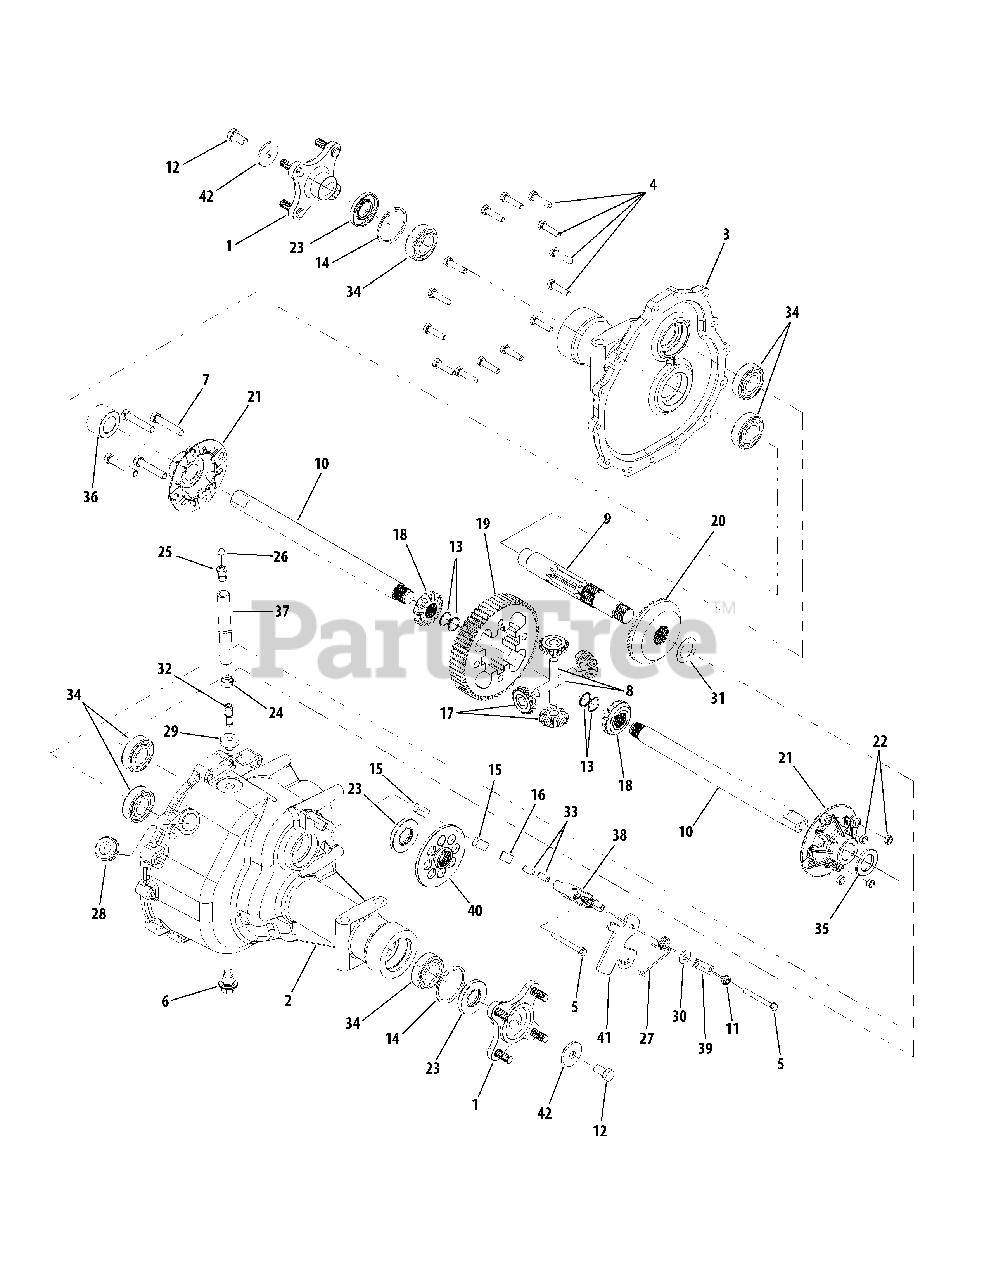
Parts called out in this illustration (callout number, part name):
1	Hub Ass’y, Wheel
2	Housing, RH Transmission
3	Housing, LH Transmission
4	Screw, Hex Cap Lock, 5/16-18 x 1.25 GR5
5	Screw, Hex Wash Hd. Tapp, 1/4-20 x 2.375
6	Screw, Plug, M14 x 1.5 x .827
7	Screw, Hex Cap Lock, 3/8-16 x 2.0 GR5
8	Shaft, Cross, .50 x 3.005
9	Shaft, Output, 9T
10	Shaft, Axle
11	Nut, Hex Nylon Lock, 5/16-24
12	Screw, Hex Cap Lock, 3/8-16 x .75 GR5
13	Ring, Retaining
14	Ring, Retaining
15	Pad, Brake
16	Plate, Puck
17	Gear, Miter, 10T
18	Gear, Miter, 14T
19	Gear, Differential Spur, 60T
20	Gear, Bevel, 54T
21	Housing, Differential w/Thru Holes
22	Nut, Hex Insert Jam GR5, 3/8-16
23	Seal, Oil, 1.0 x 2.047 x .2755
24	Clamp, Hose
25	Vent, Plastic
26	Cap, Plastic Vent
27	Spring, Torsion
28	Grommet, Rubber, .75 x 1.063
29	Grommet, Rubber, .362 x .56
30	Washer, Flat, .343 x .88 x .062
31	Washer, Thrust, 1.007 x 1.542 x .03
32	Fitting, Tube
33	Pin, Brake Actuating
34	Bearing, Ball (6205-1)
35	Spacer, Axle, 1.007 x 1.665 x .141
36	Spacer, Axle, 1.007 x 1.665 x .989
37	Tube, Transmission Breather
38	Yoke, Brake
39	Bracket, Brake Anti Rotation
40	Disc, Brake
41	Arm, Brake Actuater
42	Washer, Flat, .39 x 1.5 x .134
